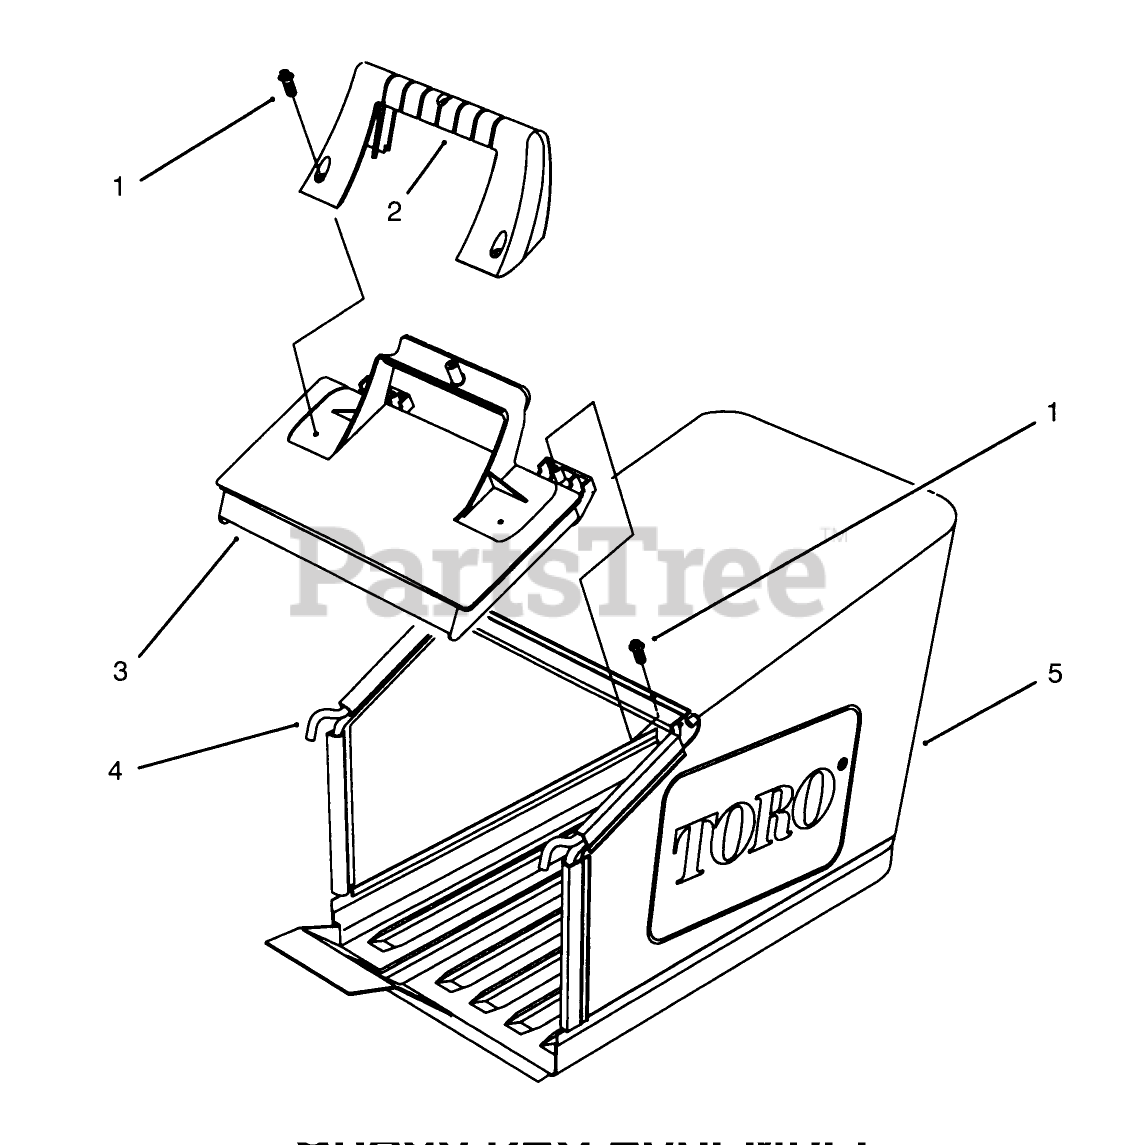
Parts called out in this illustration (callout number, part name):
1	SCREW-THD ROLL, HWH
2	HANDLE-DOOR
3	DOOR-BAG
5	GRASS BAG 48CM W/PAN
